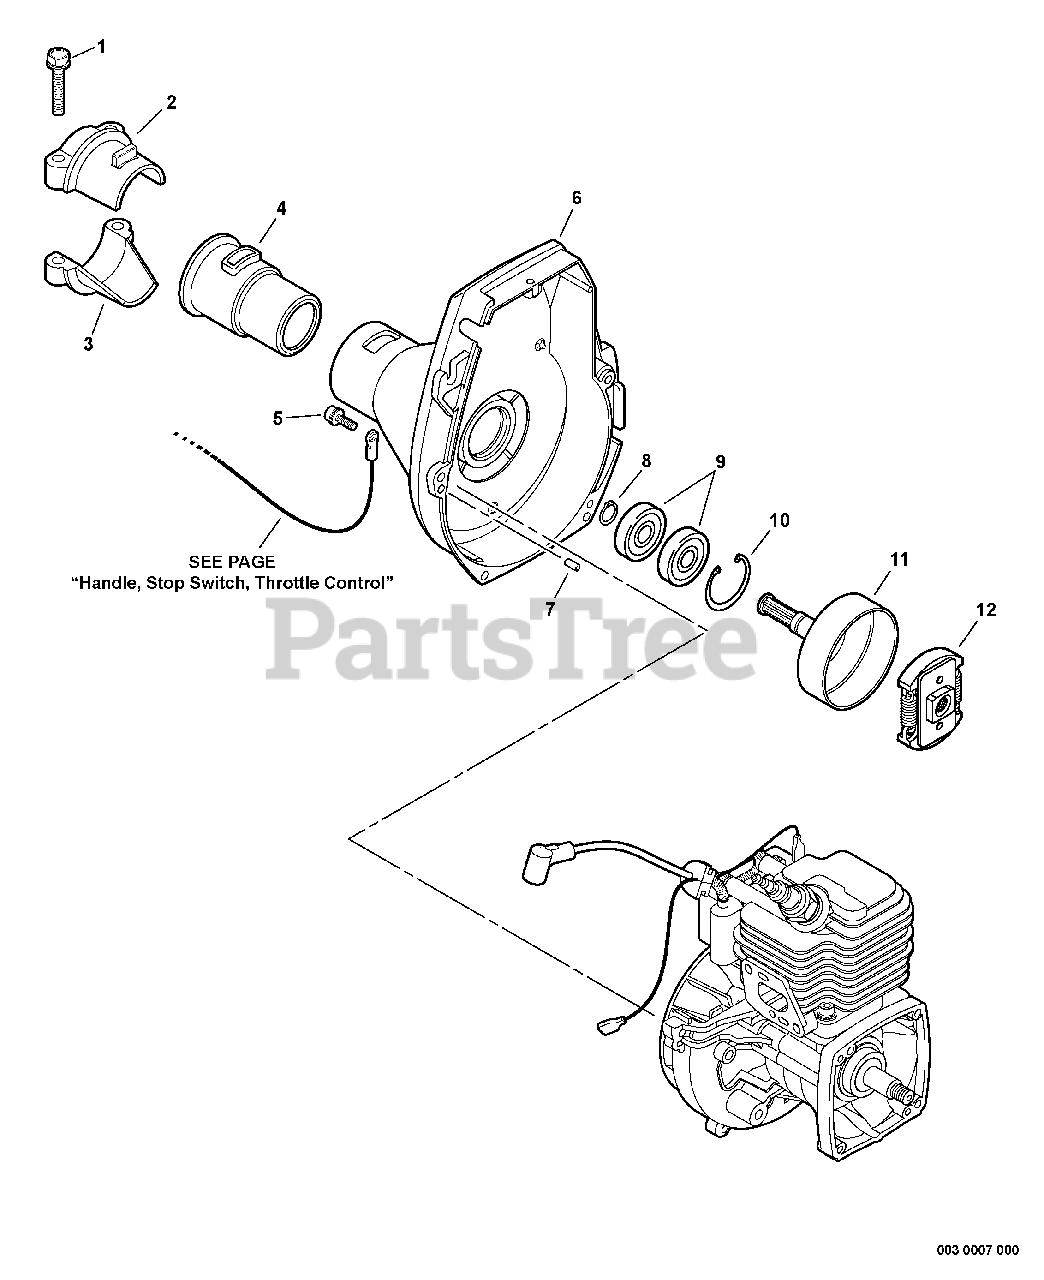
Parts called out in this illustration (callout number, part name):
1	BOLT - 5X25
2	CLAMP, MAIN PIPE - UPPER
3	CLAMP, MAIN PIPE - LOWER
5	SCREW - 4X16
6	CASE, FAN
7	PIN - LOCATING
8	RING, RETAINING - 12
9	BEARING, BALL - 6001
10	RING, RETAINING - 28
11	DRUM, CLUTCH
12	CLUTCH ASSY
